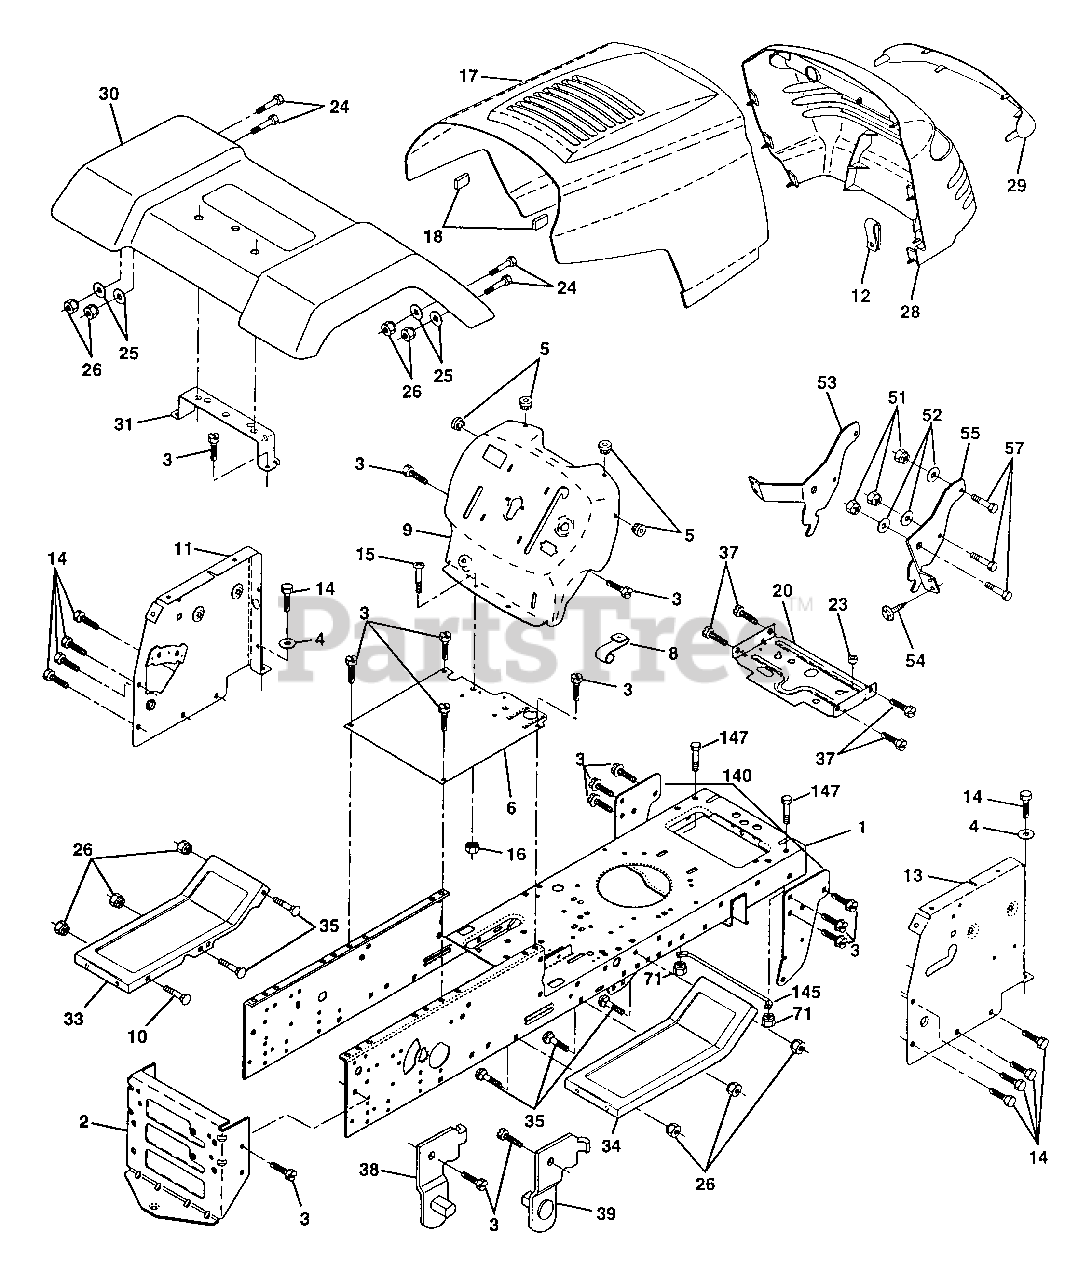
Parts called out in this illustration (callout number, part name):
1	Chassis Weldment (AYP part number)
2	Drawbar, Stretch (AYP part number)
3	Screw Thdrol 3/8-16 x 3/4 Ty-tt
4	Washer 13/32 x 3/4 x 16 Ga.
5	Bumper Hood/Dash
6	Saddle LT Fender Shift
8	Clip Retainer Slide-On
9	Dash Private Label
10	Bolt Carriage 3/8-16 x 1 (AYP part number)
11	Panel Dash Lh (AYP part number)
12	Clip Tinnerman
13	Panel Dash Rh
14	Screw Thdrol 3/8-16 x 1/2 Ty-tt
15	Screw Mach TRHD 5/16-18 unc X 3/4
16	Nut Keps 5/16-18 unc
17	Hood LT/PL
18	Bumper Hood
20	Plate Mtg Battery Fuel Tank Fr (AYP part number)
23	Bushing (AYP part number)
24	Bolt Fin Hex 3/8-16 unc X 1
25	Washer 13/32 X 13/16 X 12 Ga
26	Nut Lock Hex W/Ins 3/8-16 Unc
28	Grille LT/PL
29	Lens LT/PL
30	Fender Pnt
31	Bracket Pnt Fender
33	Footrest Pnt Lh
34	Footrest Pnt Rh (AYP part number)
35	Bolt Rdhd Sht Sqnk 3/8-16 X 3/4
37	Screw Thdrol 6/16-18 x 1/2 TYT
38	Bracket, Asm. Pivot, L.H., Mower Rear
39	Bracket, Asm. Pivot, R.H., Mower Rear
51	Nut lock Hex W/Ins 1/4-20
52	Washer 9/32 x 7/8 x 16 Ga.
53	Bracjet Grukke Lh
54	Screw Lock Spider #8 x 7/8
55	Bracket Grille Rh
57	Bolt Hex 1/4-20 x 3/4 (AYP part number)
71	Nut Crownlock 1/4-20 UNC (AYP part number)
140	Bracket Suspension Front
145	Rod Pivot Chassis/Hood
147	Bolt Hex Hd 1/4-20 UNC x 3/4
